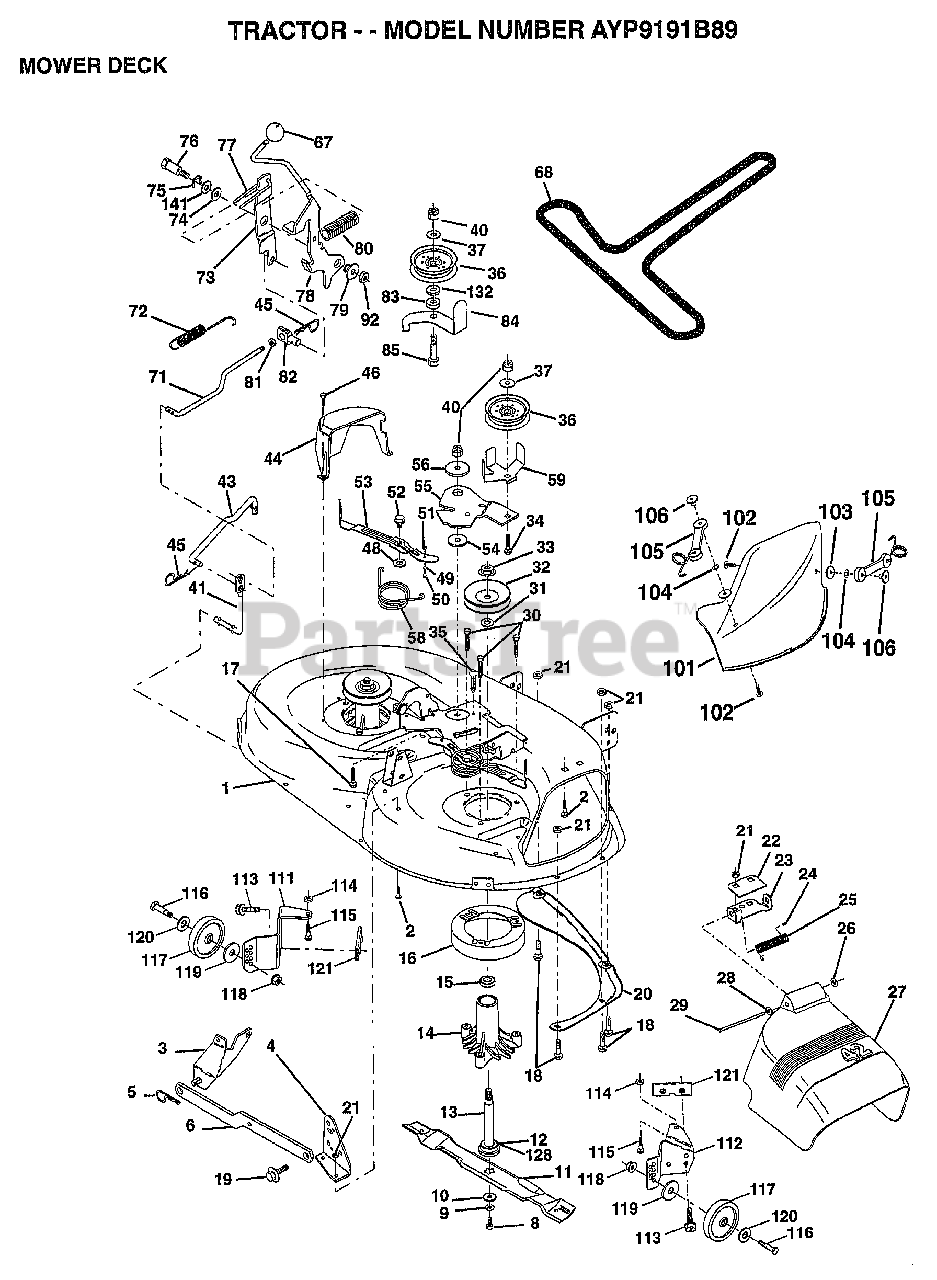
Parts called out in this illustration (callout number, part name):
1	DECK.WELD.42.
2	BOLT
3	BRKT ASM SWAY BAR
4	BRKT DECK SW BAR
8	BLADE BOLT
10	WASHER.HARD.BLADE
11	"BLADE.42"" MULCHER"
12	BEARING.BALL
14	HSG ASM MANDREL
15	BEARING
16	STRIPPER RND MWR
17	BOLT RDHD 3/8-16
18	BOLT
19	BOLT SHD 5/16-18
20	BAFFLE VORTEX 42
22	STIFFENER BRKT
23	DEFLECTOR BRKT
25	SPRING TORSION
27	DEFLECTOR.SHIELD
28	WASHER
29	HINGE ROD
30	"SCREW-THD ROLL,WA"
31	WASHER
32	PULLEY.MANDREL.42
34	BOLT
35	XMAS TREE FASTNER
36	FLAT IDLER PULLEY
37	WASHER
41	PIVOT ROD
43	ROD CLUTCH W/NIBS
44	GUARD MAND LH BLK
46	SCREW.1/4-20X5/8
48	HARD SMALL WASHER
49	ROLLER ASM-CAM
50	SHOULDER BOLT
51	LOCKNUT
52	BOLT.SHLD.5/16-18
53	BRAKE PAD ARM ASM
54	HARDENED WASHER
55	ARM-IDLER
56	SPACER RETAINER
58	SPRING TORSN BRAK
59	GUARD IDLER TUV
67	KNOB.RD.7/16-14
68	BELT.V.T-PATH
71	ROD CLUTCH 38/42
72	RETURN SPRING
73	CLUTCH ARM SECOND
74	WASHER
75	RING
76	SHOULDER BOLT
77	SPRING KEEPER
78	LEVER.ASM.CLUTCH
79	BUSHING
80	SPRING.CLUTCH.MWR
81	NUT
82	TRUNION ADJ
83	WASHER
84	"KEEPER-BELT,FIXED"
85	BOLT
92	NUT
101	"COVER.MULCH.42"""
102	SCREW
103	WASHER #10
104	LOCKWASHER
105	LATCH ASSY.BAGGER
106	WELDNUT
111	BRACKET.GWHL.LH.
112	BRACKET.GWHL.RH.
113	SCREW
116	BOLT M
117	WHEEL.GAGE.BLK.PL
118	LOCKNUT
119	WASHER
120	WASHER
121	BRACKET.EXTRD.GWL
128	WASHER.FELT.
132	WASHER GT
141	WASHER .T
